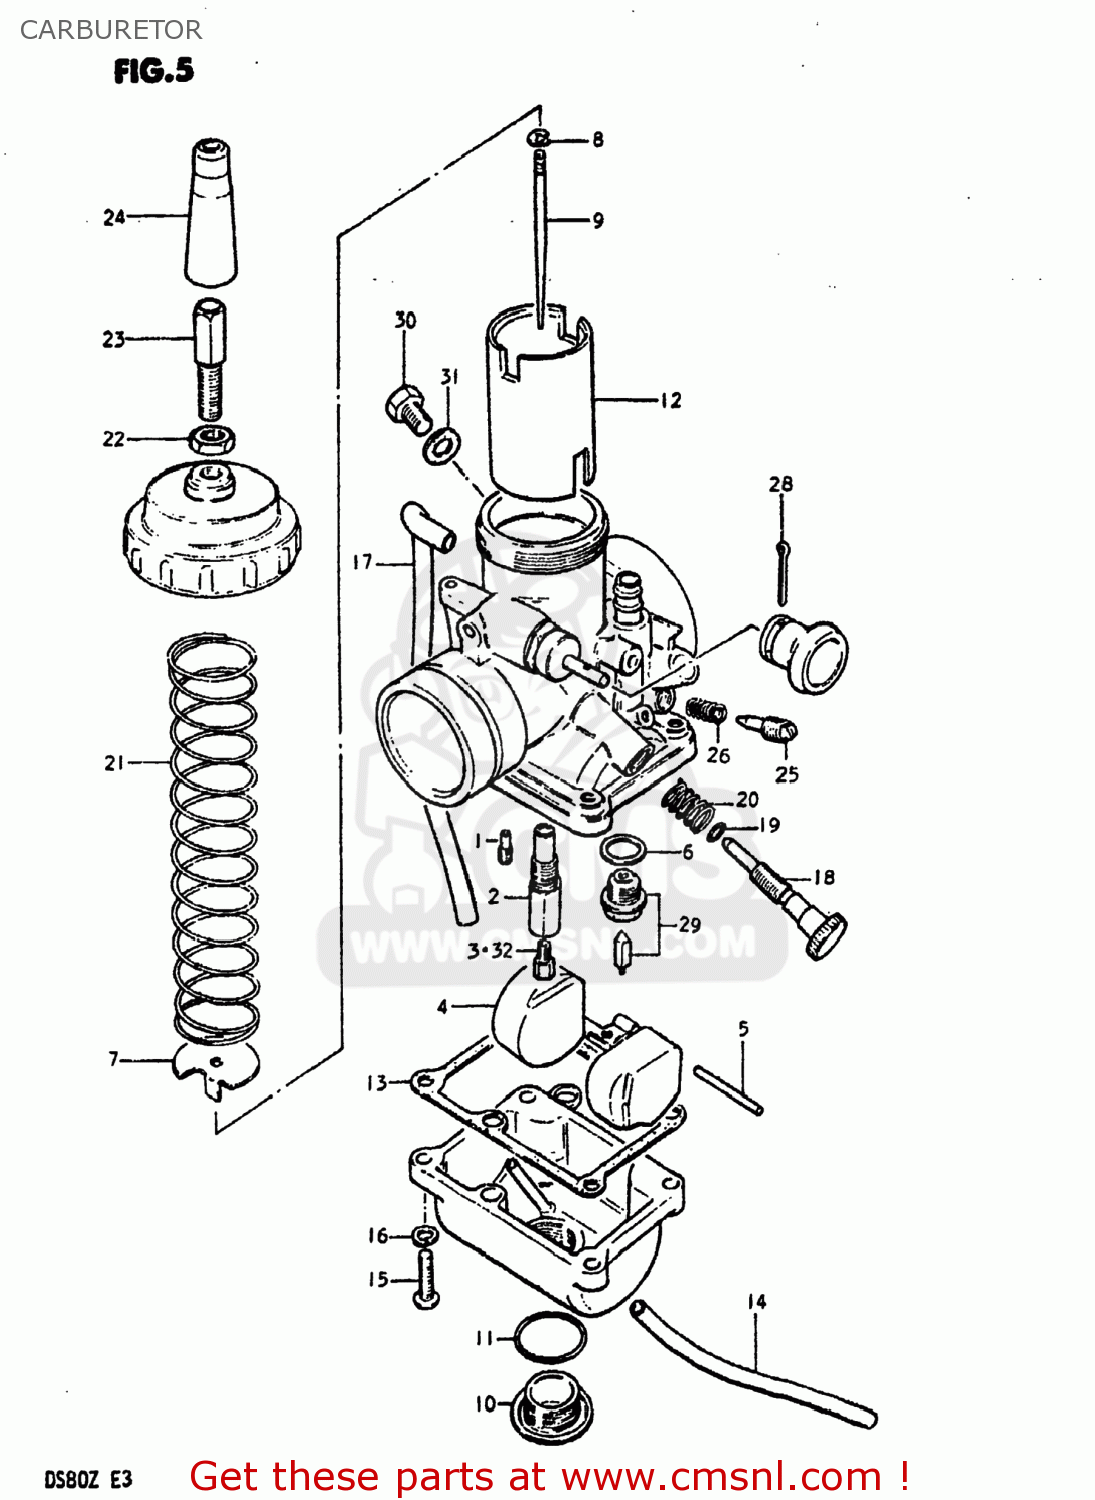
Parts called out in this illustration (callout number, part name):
1	JET,PILOT
2	JET,NEEDLE
3	JET,MAIN
4	FLOAT
5	PIN,FLOAT
6	GASKET,NEEDLE VALVE (NAS)
7	STOPPER,NEEDLE CLIP
8	CLIP
9	NEEDLE,JET
10	SCREW,GUIDE
11	O-RING
12	VALVE,THROTTLE
13	GASKET,FLOAT CHAMBER (NAS)
14	HOSE
15	SCREW
16	LOCK WASHER
17	HOSE
18	ADJUSTER
19	O-RING
20	SPRING
21	SPRING,THROTTLE VALVE
22	NUT
23	ADJUSTER,CABLE
24	CAP,CABLE ADJUSTER
25	SCREW,PILOT AIR
26	SPRING
27	LEVER
28	COTTER PIN
29	VALVE ASSY,NEEDLE
30	BOLT
31	GASKET,THRO VALVE INSPECTION (NAS)
32	JET,MAIN
